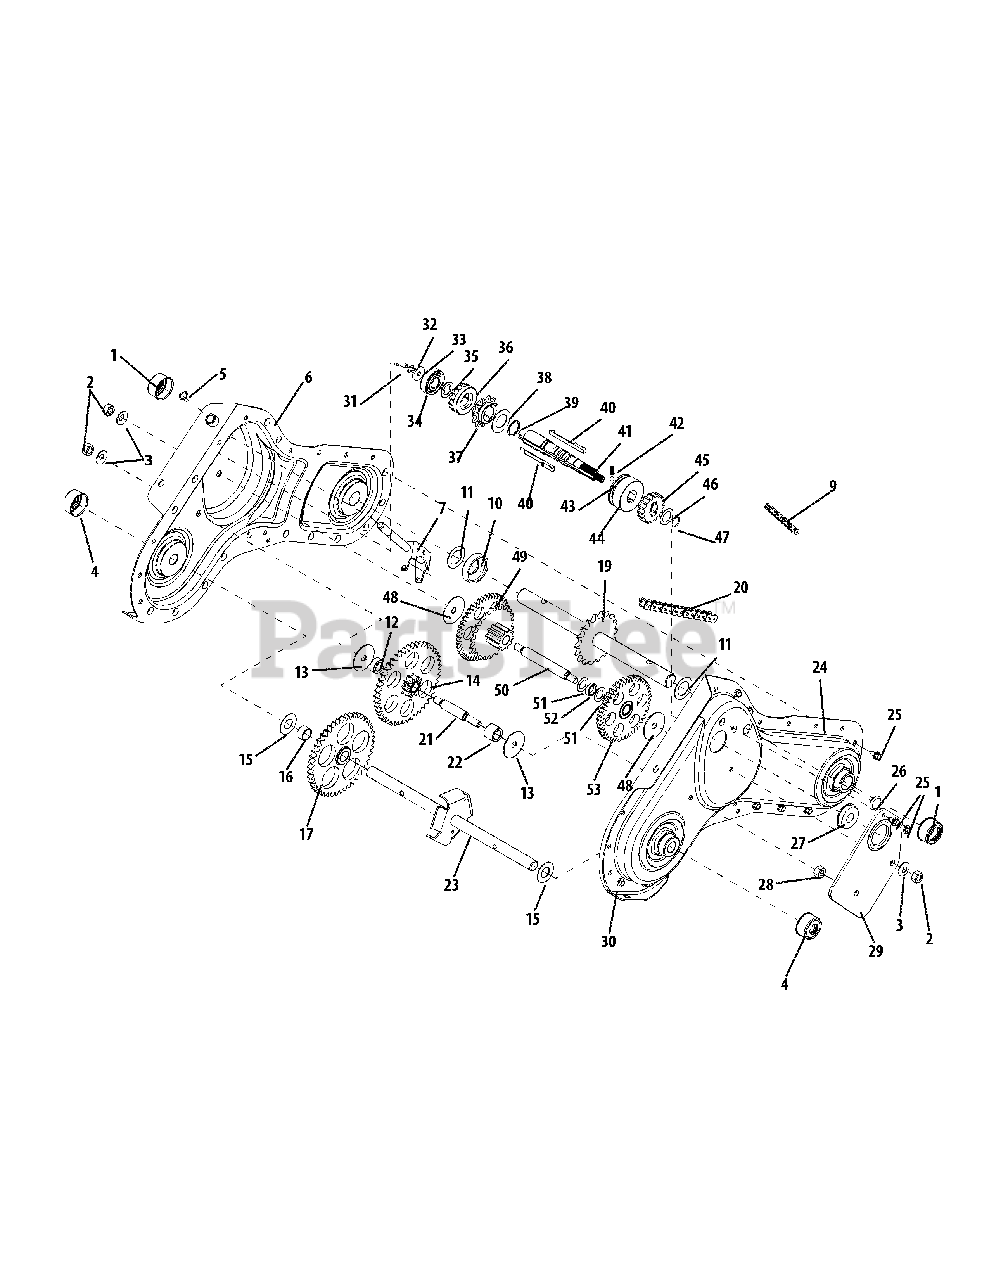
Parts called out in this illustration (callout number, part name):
1	Shaft Seal, 1.0 Dia
2	Hex Nut, 7/16-20
3	Bell Washer, .45 ID x 1.0 OD
4	Shaft Seal, .75 Dia
5	Snap Ring, .50 Dia
6	Gear Case Assembly, Right Half
7	Shift Assembly
9	Chain, #41 1/2" Pitch x 30 Links
10	Space, 1.0 ID x 2.0 OD
11	Thrust Washer, 1.03 ID x 1.62 OD
12	Spacer, .635 ID x 1.0 OD
13	Thrust Washer, .445 ID x 1.92 OD
14	Idler Gear Assembly
15	Flat Washer, .760 ID x 1.50 OD
16	Spacer, .735 ID x.886 OD
17	Spur Gear, 46T
19	Tine Shaft Assembly, 18T
20	Chain, #50 5/8" Pitch x 52 Links
21	Jack Shaft, 5/8 Dia. X. 2.06 Lg
22	Spacer, .635 ID x 1.0 OD
23	Wheel Shaft Assembly
24	Gear Case Assembly, Left Half
25	Hex Washer Screw, 1/4-14 x.625
27	Ball Bearing w/Snap Ring
28	Hex Patch Lock Nut, 7/16-20
29	Reinforcement Bracket
30	Chain Case Gasket
31	Hex Cap Screw, 1/4-20 x.625
32	Lock Washer, 1/4
33	Flat Washer, .281 ID x.875 OD
34	Ball Bearing
35	Flat Washer
36	Spur Gear, 16T
37	Sprocket, 11T #41 Chain
38	Flat Washer, .88 ID x 1.50 OD
39	Retainer Ring
40	Clutch Key
41	Drive Shaft
42	Compression Spring
43	Detent Ball
44	Clutch Collar
45	Spur Gear, 17T
46	Flat Washer, .69 ID x 1.06 OD
47	Wire Ring
48	Thrust Washer, .445 ID x 1.9 OD
49	Intermediate Gear Assembly
50	Jack Shaft
51	Flat Washer, .625 ID x 1.0 OD
52	Spacer, .635 ID x.86 OD
53	Tine Drive Assembly
